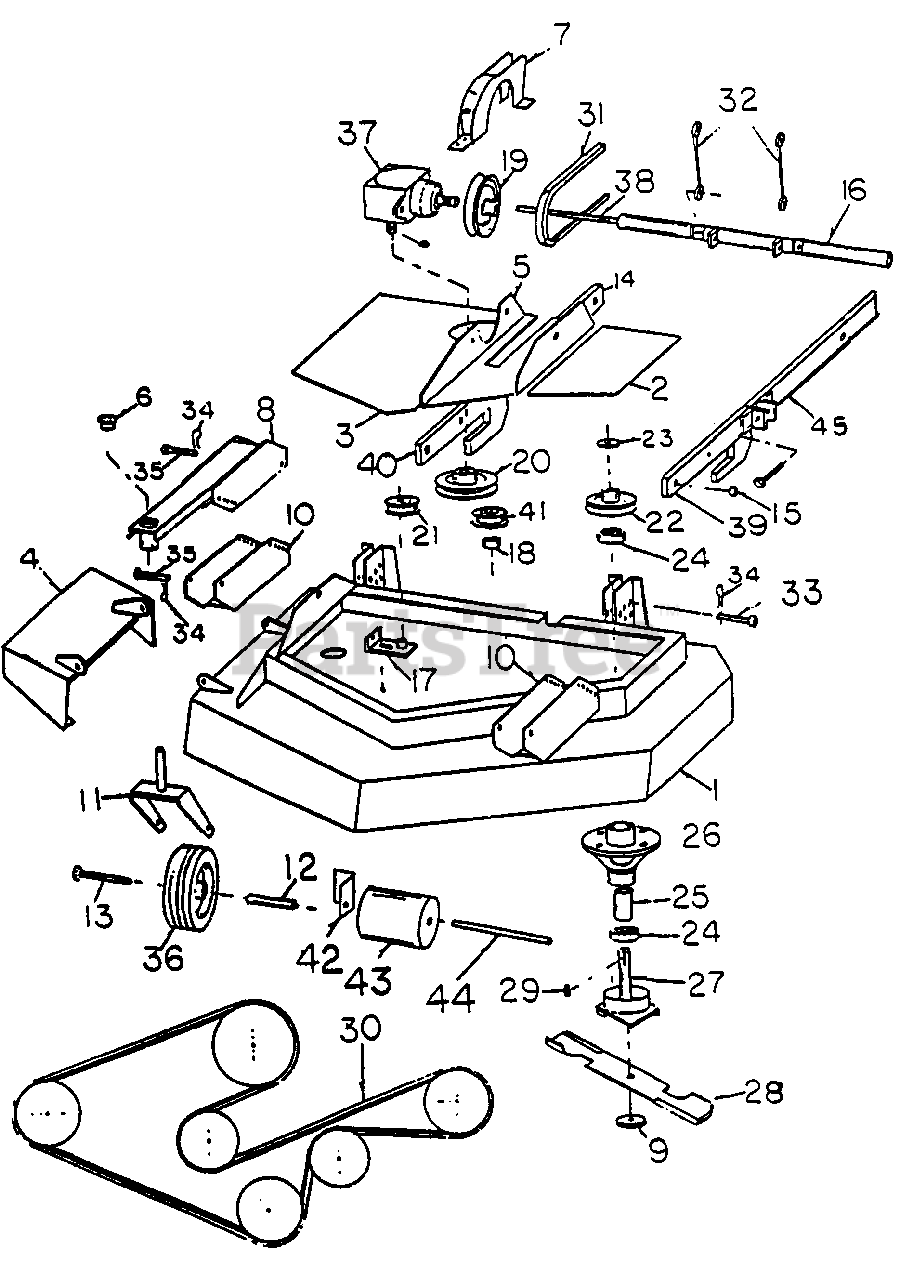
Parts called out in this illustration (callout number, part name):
3	COVER (LARGE)
4	FOOT GUARD
5	GEAR BOX MOUNT
6	GAGE WHEEL BUSHING
7	BELT GUARD
8	GAGE WHEEL MOUNT
10	BRACKET, GAGE WHEEL MOUNT
11	PORK, GAGE WHEEL
12	AXLE, GACE WHEEL
13	GAGE WHEEL BOLT
14	DECK LIFT ARM BACK ADJUSTABLE
15	BUSHING, DECK LIFT ARM
18	SPACER, IDLER
19	PULLEY, GEAR B0X
20	PULLEY, GEAR B0X
21	PULLEY, IDLER TIGHTENER
22	PUELEY, SPINDLE
23	WASHER, SPINDLE
24	BEARING, SPINDLE
25	SPACER, SPINDLE
26	HOUSING, SPINDLE
27	SHAFT, SPINDLE
29	KEY, SPINDLE
35	PINS, GAGE WHEEL
38	CROSS BAR PI
39	L.H. 1 DECK LIFT ARM FRONT ADJUSTABLE
40	R.H. 1 DECK LIFT ARM FRONT ADJUSTALE 0 R.H,
42	ROLLAR BRACKET
45	L.H. 1 DECK LIFT ARM BACK ADJUSTABLE
